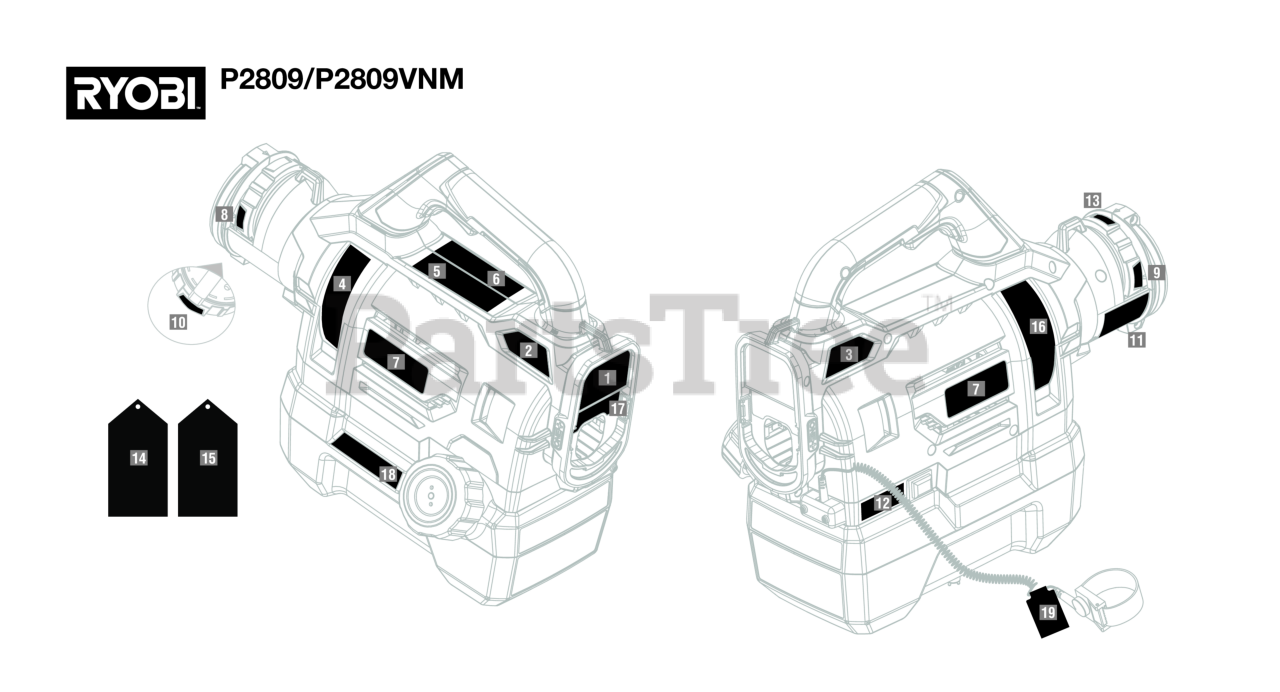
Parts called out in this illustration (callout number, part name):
1	Data Label
2	18V Label (Left)
3	18V Label (Right)
4	Electrostatic Logo Label (Left)
5	Warning/Icon Label
6	Warning Label
7	Logo Label
8	High Spray Nozzle Label
9	Low Spray Nozzle Label
10	Medium Spray Nozzle Label
11	Caution Label
12	ES On/Off Label
13	Remove/Eject Puck Label
14	Cleaning Nozzle Reference Guide Hang Tag (EN/FR/SP)
15	Cleaning Nozzle Reference Guide Hang Tag (PORT)
16	Electrostatic Logo Label (Right)
17	Clean Tank and Lines Label
18	Max Fill Label
19	Anti-Static Cord Wrap
